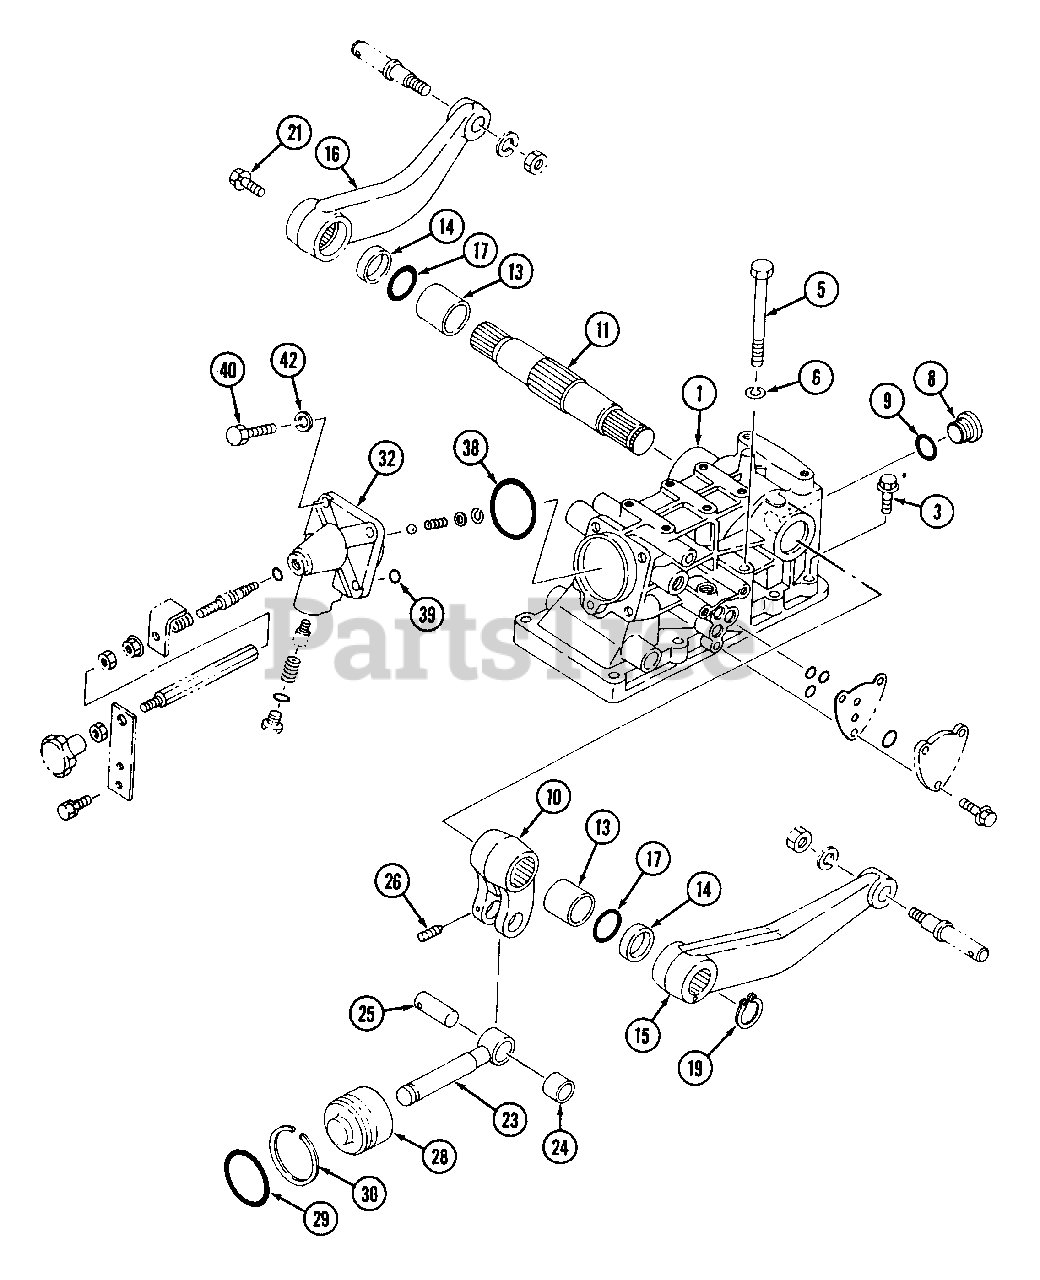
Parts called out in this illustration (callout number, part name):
1	Case, Hydraulic
11	Shaft, Hydraulic
15	Arm, Lift L
16	Arm, Lift R
32	Head, Cylinder
